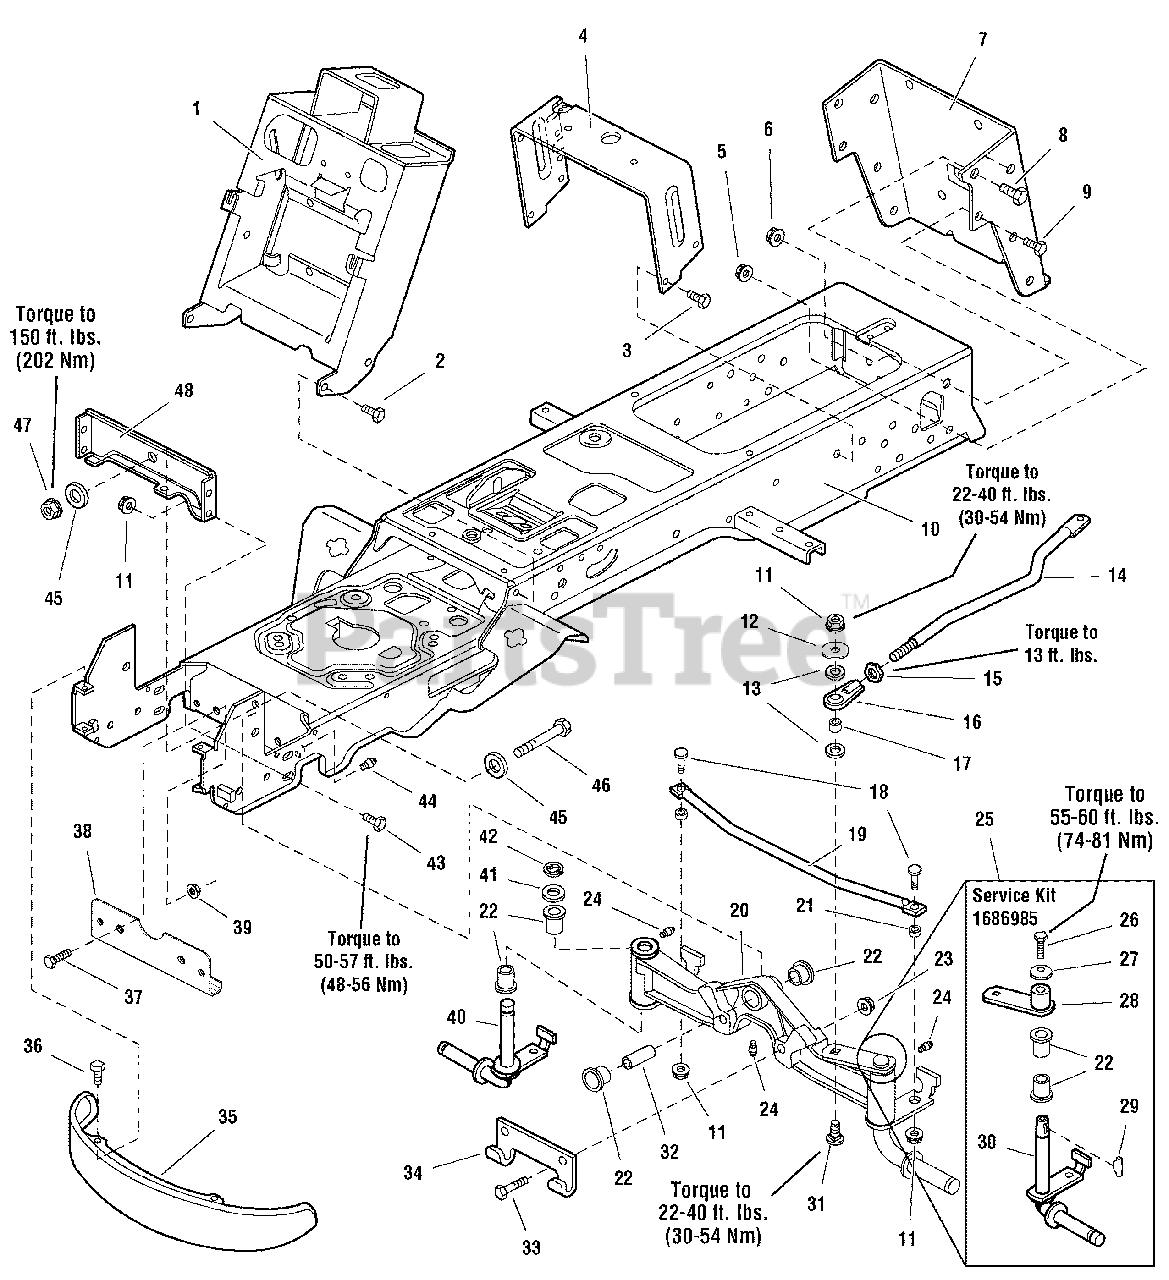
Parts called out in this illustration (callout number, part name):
1	TOWER & SUPPORT ASSEMBLY
2	CAPSCREW, Hex Washer Head, Taptite, 3/8-16 x 3/4
3	SCREW, Taptite, 5/16-18 x 3/4
4	SUPPORT, Seat Deck
5	NUT, Hex Flange Whiz Lock, 3/8-16 Large
6	NUT, 1/2-13 Hex Flange Two-Way Lock Black
7	BACKPLATE, Hitch
8	CAPSCREW, Hex Head 1/2-13 x 1, Black
9	CAPSCREW, Hex Head, 3/8-16 x 1, G5
10	FRAME ASSEMBLY, Front & Rear
11	NUT, Hex Flange, Two Way Lock, 3/8-16
12	WASHER, Flat, 13/32
13	WASHER, 3/8" Flat- Black
15	NUT, Hex Head, 1/2-20, Black
16	JOINT-BALL .500-20 THD .500ID, CLR ZINC
17	SPACER, 0.377 x 1/2 x 5/8"
18	BOLT, Carriage, 3/8-16 X 1, G5
20	AXLE ASSEMBLY, w/ LH Spindle, Complete (Includes Ref. Nos. 22, 24, 41, 42 & 43)
21	SPACER, 3/8 ID x 5/8 OD x 5/16"
22	BUSHING, 31/32 x 1-1/4 x 3/4, Powder Metal
23	NUT, Hex Two Way, 7/16-14
24	FITTING, Grease
25	SPINDLE REPLACEMENT KIT, LH (Includes Ref. Nos. 22, 26, 27, 28, 29 & 30)
26	CAPSCREW, Hex Hd., 3/8-16 x 7/8, Gr. 8
27	WASHER, Spring, 3/8
28	HUB & ARM ASSEMBLY
29	KEY, Hi-Pro, 1/4 x 3/4
30	SPINDLE, LH
31	BOLT, Carriage, Short Neck, 3/8-16 x 1-1/2, G5
32	SPACER, 0.641ID x 0.978OD x 2.082LG
33	CAPSCREW, hex Head, 7/16-14 x 2, G8, Black
34	HOOK, Mower, Hitch
35	BUMPER, Black, Steel, Standard
35	WASHER, 1, (As Required for All Front, As Required for K62 Rear)
36	SCREW, Truss Head Torx, 5/16-18 x 7/8
37	SCREW, Hex Flange Whiz Lock, 3/8-16 x 3/4
38	FITTING, Grease
39	WASHER, 5/8
40	SPINDLE ASSEMBLY, RH
41	WASHER, 1, (As Required for All Front, As Required for K62 Rear)
42	RING, Retainer
43	SCREW, Hex Flange Whiz Lock, 3/8-16 x 3/4
44	FITTING, Grease
45	WASHER, 5/8
46	CAPSCREW, Hex Head, 5/8-11 x 3-1/2, GR5
47	NUT, Hex Flange, 5/8-11
48	PLATE, Axle Support
